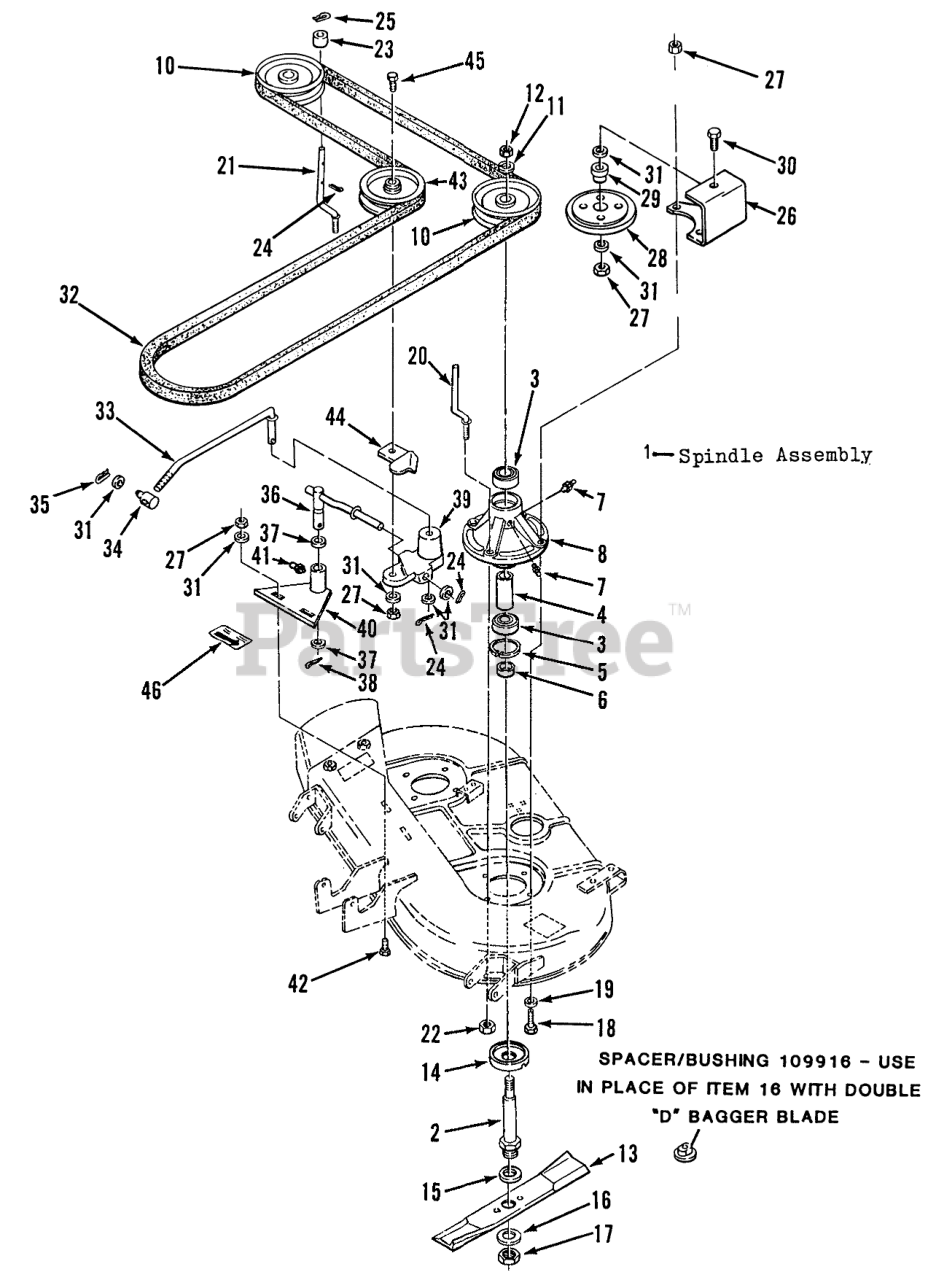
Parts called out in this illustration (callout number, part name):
1	ASSY SPINDLE R
2	SHAFT SPINDLE
3	BEARING-BALL
5	Ring-Snap
6	SPACER-BLADE
7	Fitting-Grease
8	HOUSING SPINDLE
11	Lockwasher
12	Jam Nut
13	ASSY BLADE KIT
14	CUP-SPINDLE
15	Washer
16	SpeciaI Washer
17	Nut-Jam
18	BOLT
18	Screw-Hex Hd.
19	LOCKWASHER
22	NUT
24	Pop Rivet
25	Hairpin
30	Bolt
31	Washer
35	Hairpin Cotter
37	WASHER SPECIAL
38	Cotter Pin
39	BLOCK IDLER
40	IDLER BRACKET ASS R
41	FITTING-GREASE
42	Bolt
45	Bolt
46	DECAL-BELT ADJUST
